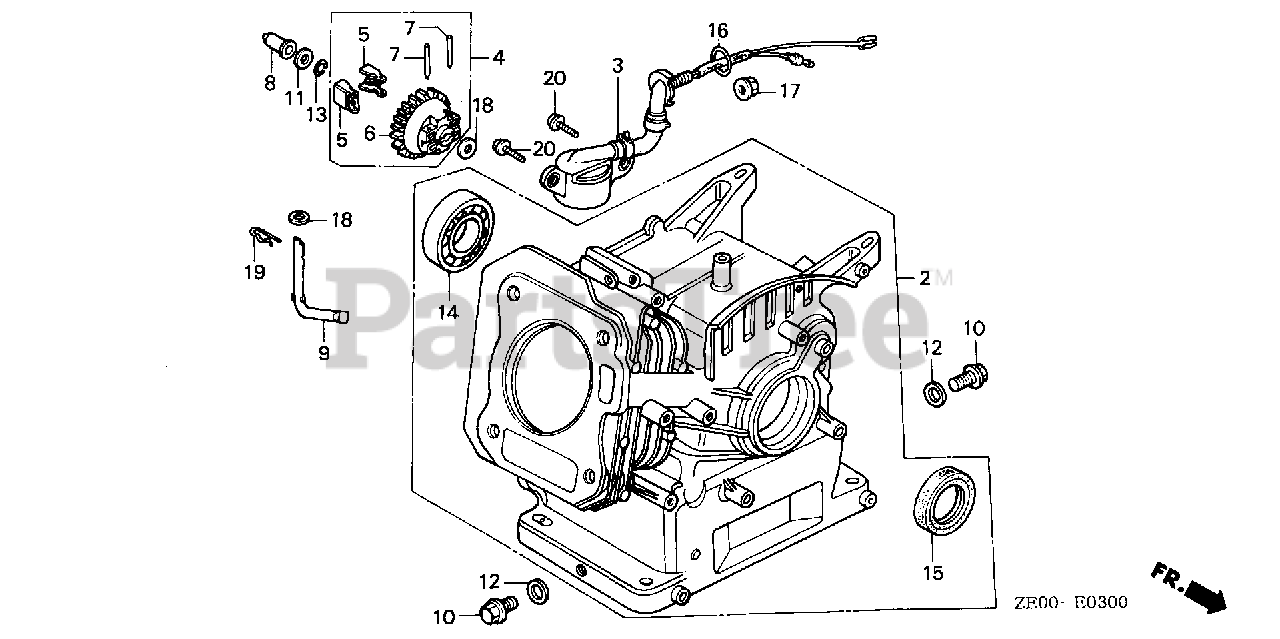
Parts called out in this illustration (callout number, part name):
2	CYLINDER ASSY. (OIL ALERT) (NOT AVAILABLE)
2	CYLINDER ASSY. (OIL ALERT)
3	SWITCH ASSY., OIL LEVEL
4	GOVERNOR ASSY.
5	WEIGHT, GOVERNOR
6	HOLDER, GOVERNOR WEIGHT
7	PIN, GOVERNOR WEIGHT
8	SLIDER, GOVERNOR
9	SHAFT, GOVERNOR ARM (NOT AVAILABLE)
9	SHAFT, GOVERNOR ARM
10	BOLT, DRAIN PLUG
11	WASHER, THRUST (6MM)
12	WASHER, DRAIN PLUG (10.2MM)
13	CLIP, GOVERNOR HOLDER
14	BEARING, RADIAL BALL
15	OIL SEAL (22X35X6)
16	O-RING (13.5X1.5) (ARAI)
16	O-RING (14MM) (NOK)
17	NUT, FLANGE (10MM)
18	WASHER, PLAIN (6MM)
19	PIN, LOCK (8MM)
20	BOLT, FLANGE (6X12)
